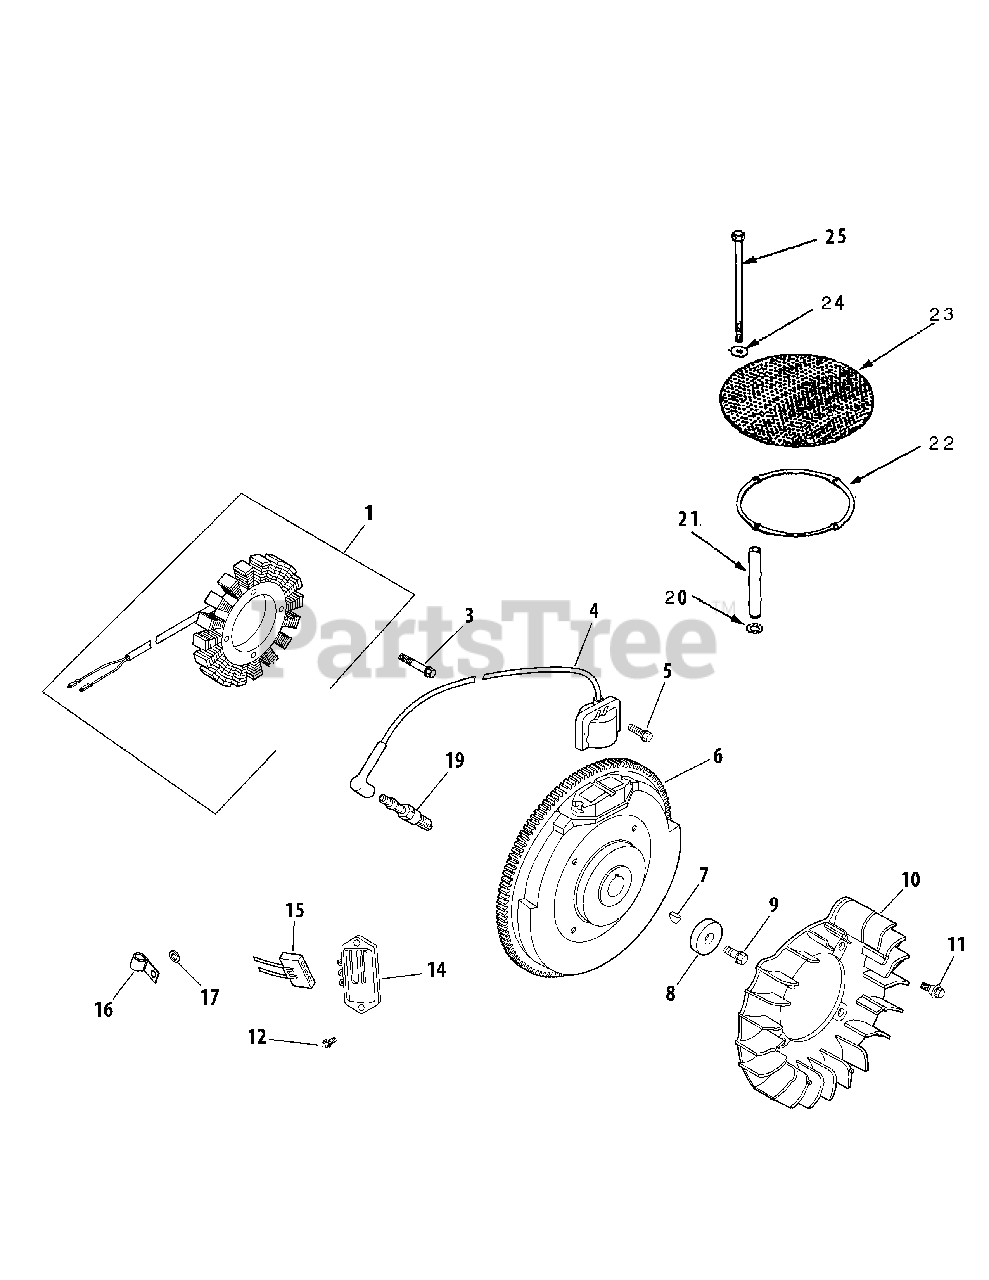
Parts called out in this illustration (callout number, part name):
1	KIT, 15/20 AMP STATOR ASSY.
3	SCREW, THD FRM M5X0.8X25
4	KIT, MODULE IGNTN (CDI FIXED)
5	SCREW, FLG THD FRM M5X.8X20
7	KEY, 3/16'' X 5/8''
8	WASHER, FLAT 13/32''
9	SCREW, FLG M10X1.5X45
10	FAN
11	SCREW, SKT SET #10-24X1/4''
12	SCREW, HEX FLANGE HI-LO
14	REGULATOR, RECTIFIER
15	HARNESS, WIRING ASSEMBLY
16	CLIP, CABLE
17	WASHER, FLAT 1/4'' (O.D. 5/8'')
19	PLUG, SPARK (STD)
20	WASHER, SPRING 10 MM
22	RING, SUPPORT
23	SCREEN, GRASS
24	WASHER, FLAT 1/4'' (O.D. 1/2'')
25	SCREW, CAP M6X1.0X99.5
